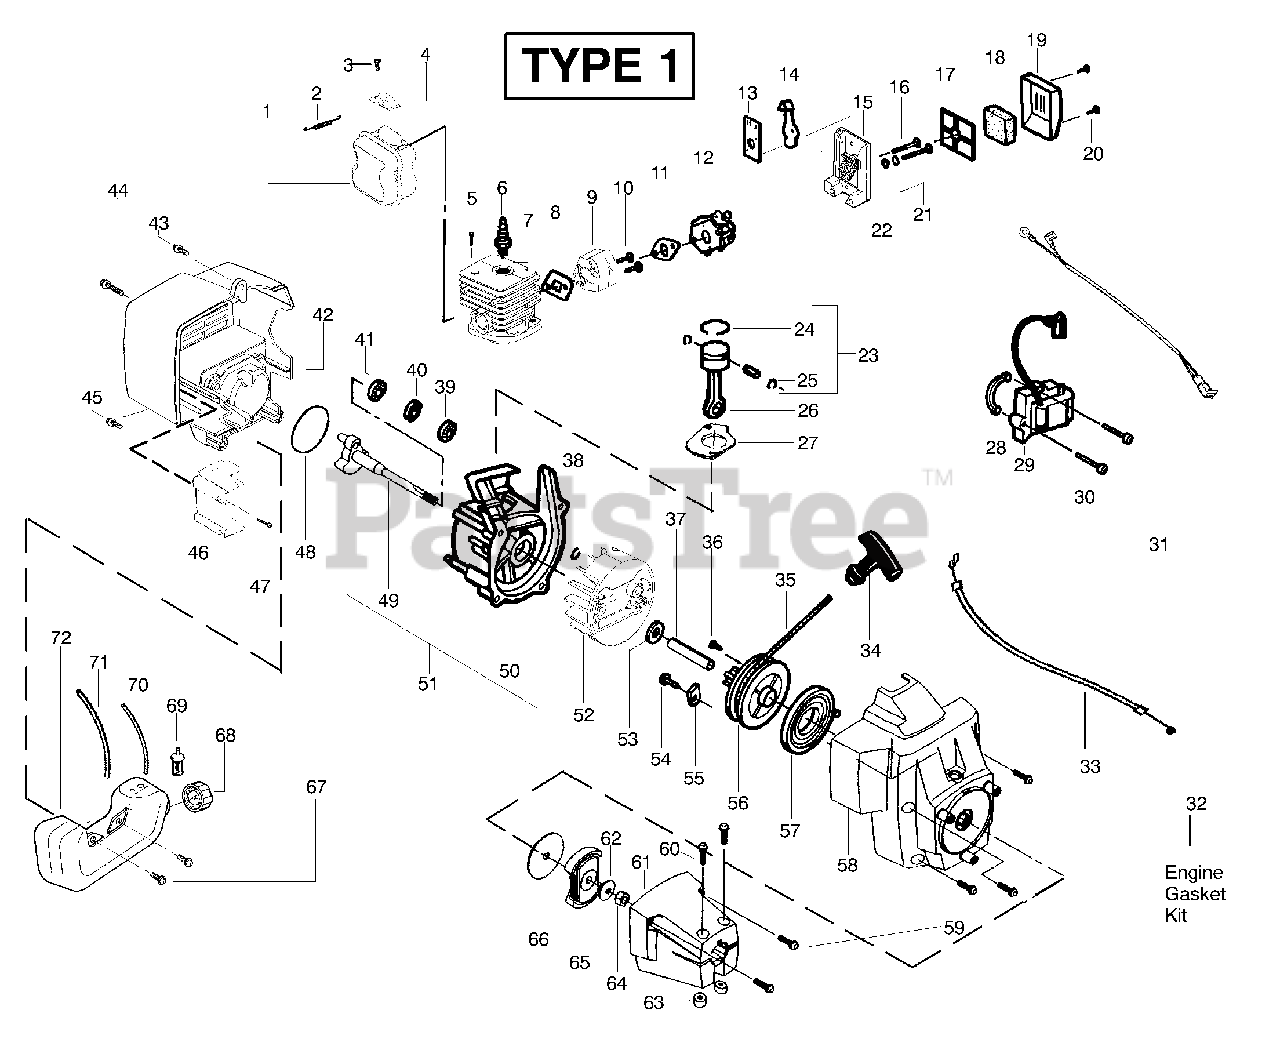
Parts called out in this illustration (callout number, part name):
1	Kit -- Muffler
2	Spring--Muffler
3	Screw--Screen
4	Kit--Spark Arrestor
5	Screw--Cylinder
6	Spark Plug (RCJ 6Y)
7	Kit -- Cylinder
8	Gasket--Cylind./Carb.
9	Adapter--Carb.
11	Gasket--Carb.
12	Kit--Carburetor (C1U--X785)
12	Kit--Carburetor (C1U--W16)
13	Choke Plate Mounting
14	Shutter--Choke
17	Plate -- Filter Support
18	Foam--Air Filter
19	Cover--Air Filter
21	Spacer--Choke
23	Kit -- Piston
24	Piston Ring
25	Retainer - Piston Rod
26	Assy - Connecting Rod
27	Gasket--Cylinder
28	Spacer--Module
29	Ignition Module
31	Assy--Switch Wire
32	Kit--Engine Gasket
33	Assy--Throttle Cable
34	Handle--Starter
35	Kit -- Rope
37	Spacer--Flywheel
38	Retain. Ring--C'shaft
39	Outer Bearing
40	Kit--C'case Seal
41	Inner Bearing
42	Shroud--Rear
44	Screw
46	Shield--Heat
47	Screw
48	O--Ring--C'case/Shrd
49	Assy--Crankshaft
50	Assy--Crankcase
51	Assy--C'case & C'shaft
52	Assy--Flywheel
55	Retainer
56	Kit--Starter Pull
57	Spring--Starter
58	Assy.--Fan Hsg
59	Screw
61	Assy--Clutch Hsg.
62	Washer--Flat
64	Nut--Clutch
65	Assy--Clutch
66	Washer--Clutch
67	Retainer
68	Assy--Fuel Cap
69	Assy--Fuel Pickup
70	Kit--Fuel Line (Small)
71	Kit--Fuel Line (Large)
72	Assy--Fuel Tank
